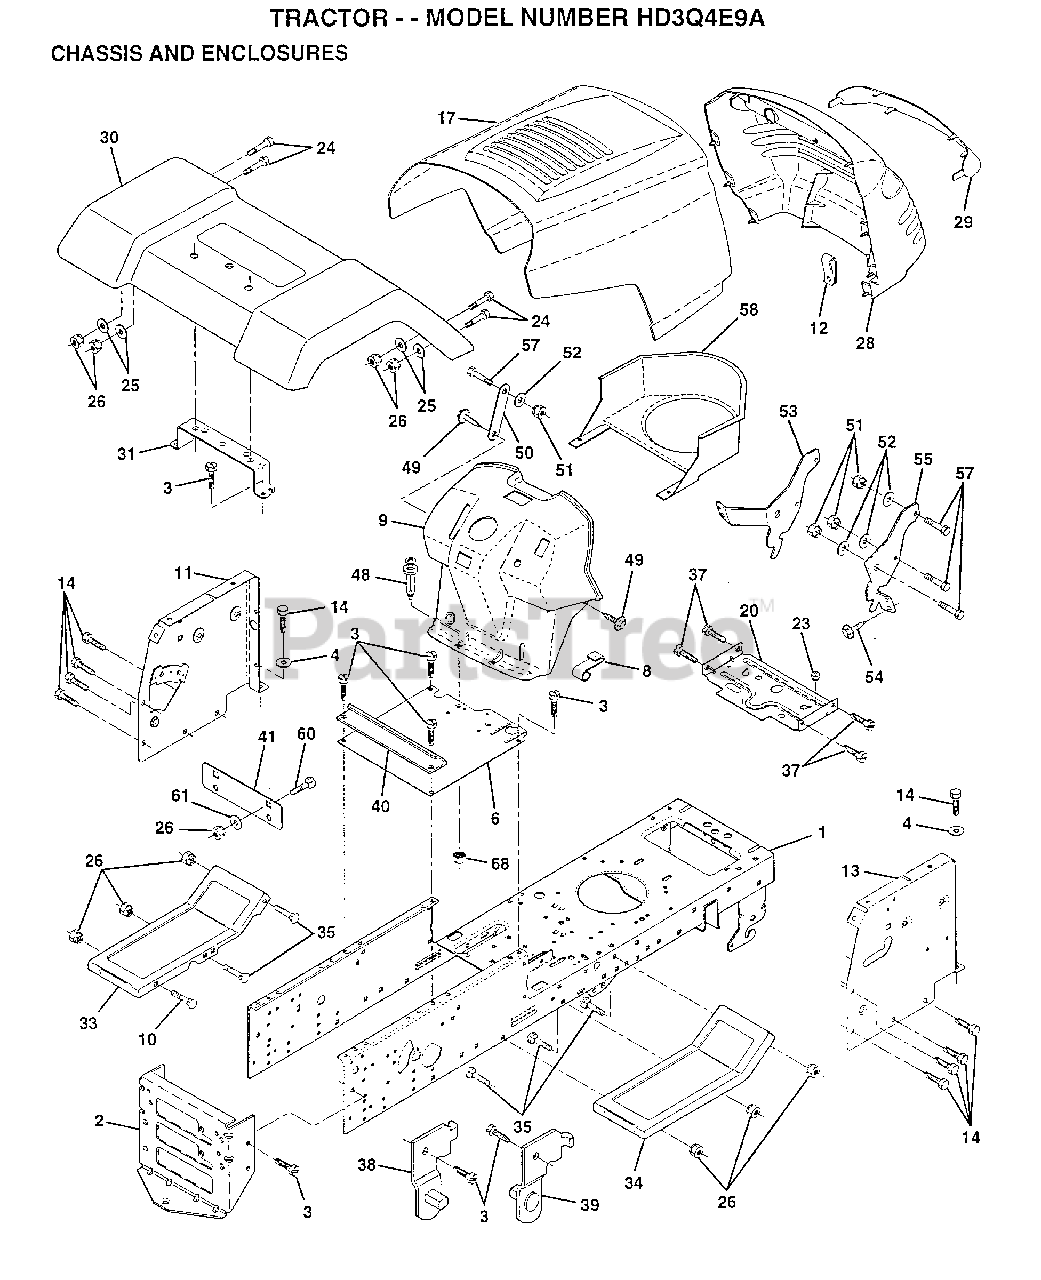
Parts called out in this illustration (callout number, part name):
1	CHASSIS.WLD.11GA
3	SCREW
4	WASHER
8	"CLIP,INSULATOR"
11	PANEL.DASH.LH.A
12	CLIP.TINNERMAN
13	PANEL.DASH.RH
14	SCREW LT
20	PLATE.MTG.BTRY.TK
24	BOLT
25	WASHER
26	NUT
29	LENS GRILLE
30	FENDER ASM LT W/S
31	BRACKET SUPT FEND
33	FOOTREST PNT LH
34	FOOTREST.RH.LT/GT
35	BOLT
37	SCREW LT
38	BRACKET ASM LH
39	BRACKET ASM RH
40	SPACER FENDER LT
41	PLATE EXTEN FEND
48	RIVET.PUSH.PLATE
49	SCREW HEX CRT
50	BRACE SUPT DASH
51	NUT
52	WASHER
53	BRACKET.GRILLE.LH
55	BRACKET.GRILLE.RH
58	DUCT.AIR.B&S.18HP
60	BOLT
61	WASHER
68	NUT
